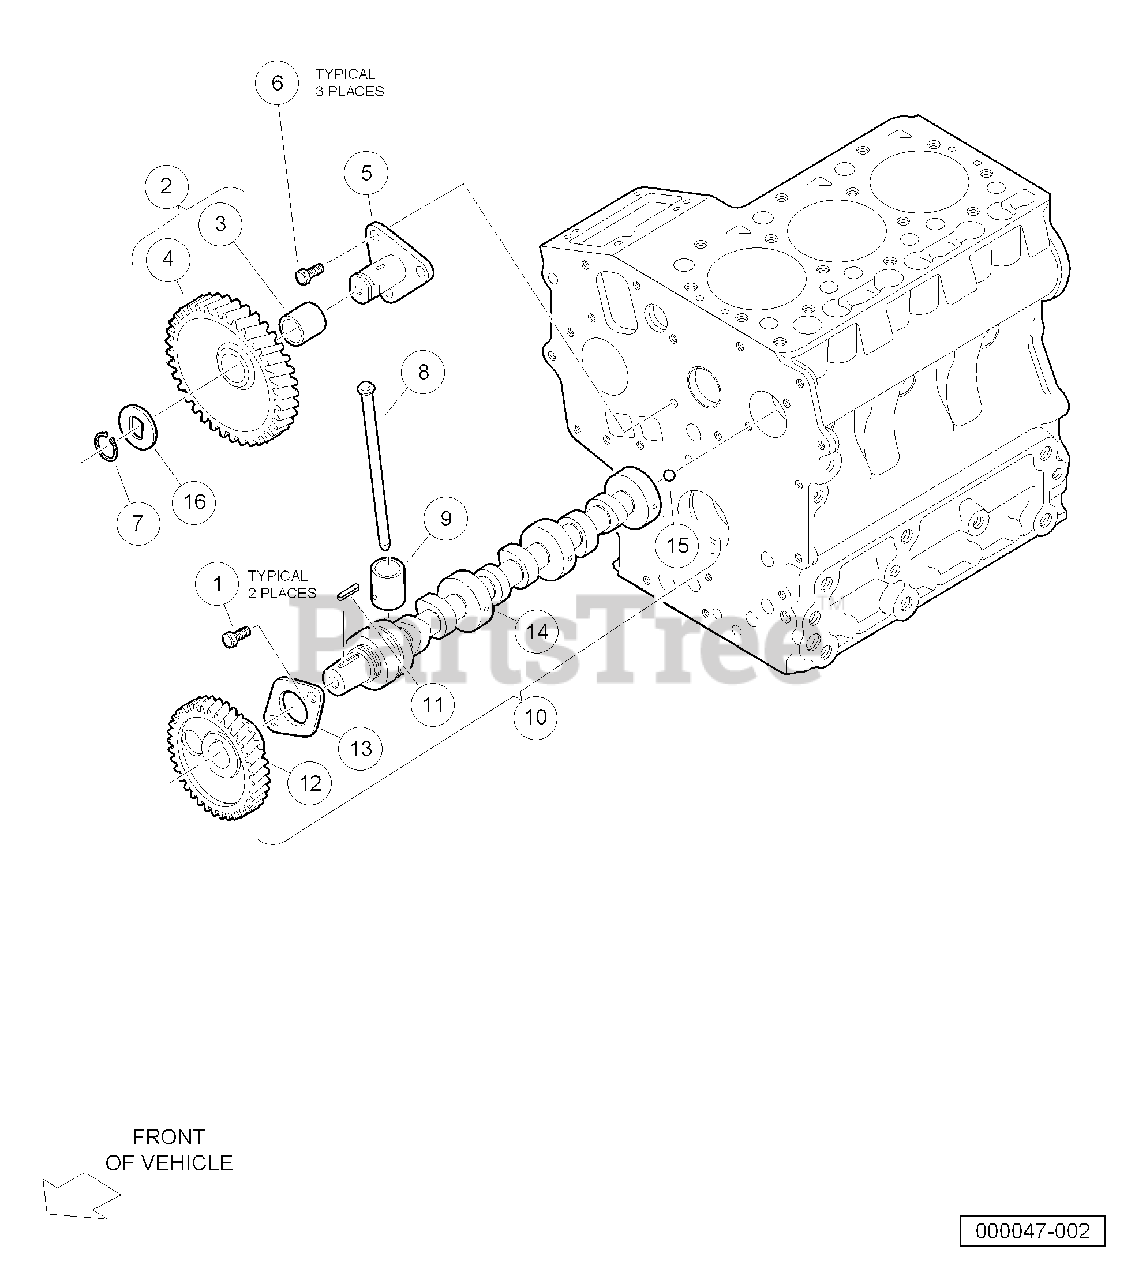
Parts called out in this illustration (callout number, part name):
1	Bolt, D722, Cam End
2	Gear, Idle
3	Bushing, D722 Idle Gear
4	Gear, Idle
5	Shaft, Idle Gear
6	Bolt, M6 X 1 X 14
7	Ring, Snap
10	Assy Camshaft, Long
11	Key, Feather, Long Camshaft
13	Stopper, Camshaft
14	Camshaft
15	Ball, Check
16	Collar, Idle Gear
